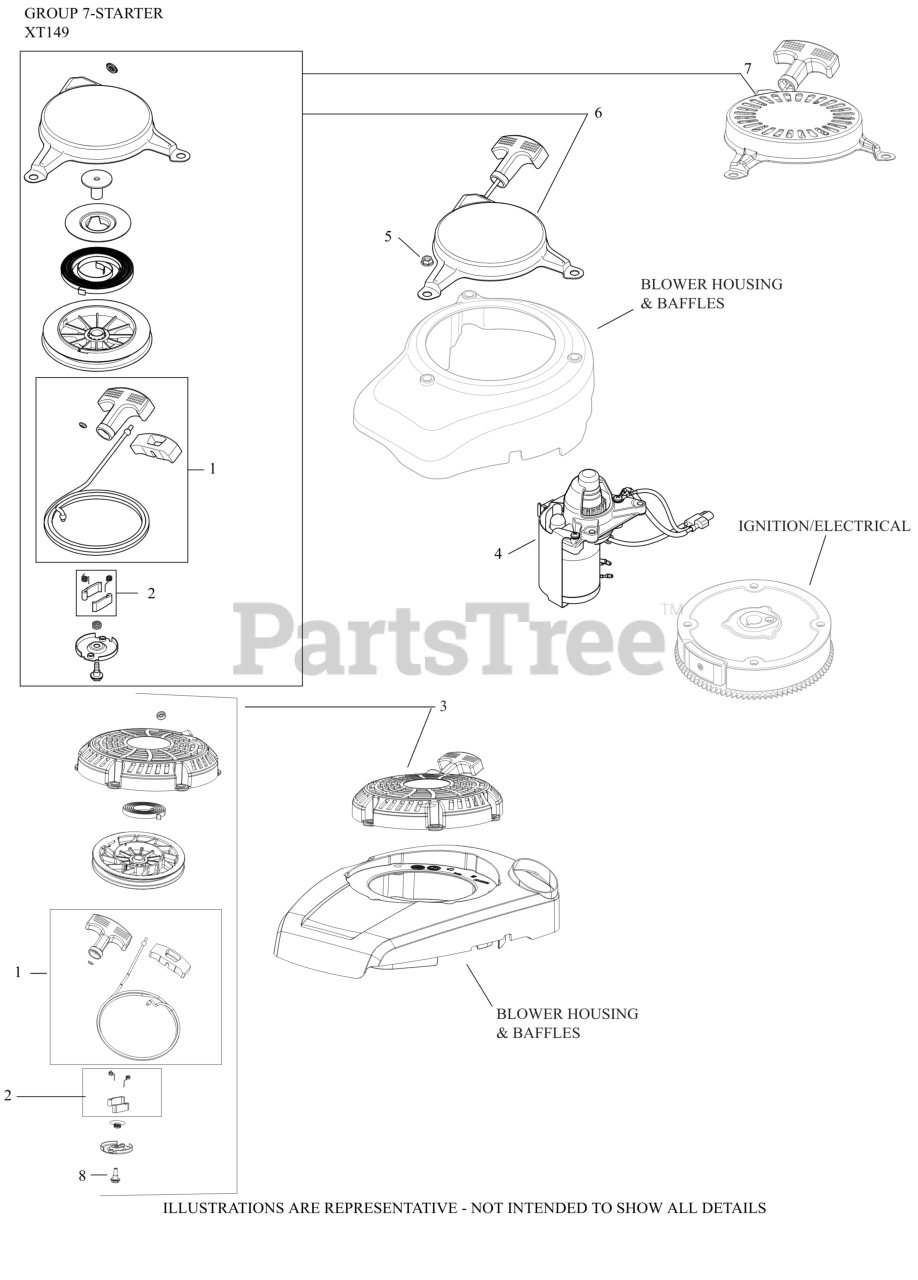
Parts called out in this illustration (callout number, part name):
1	KIT, STARTER ROPE W/HANDLE
2	KIT, PAWL REPAIR
3	STARTER ASSY-RETRACT-USE 14 165 21-S
4	ELEC STARTER-USE 14 098 06-S
8	SCREW, SHOULDER (M5)
